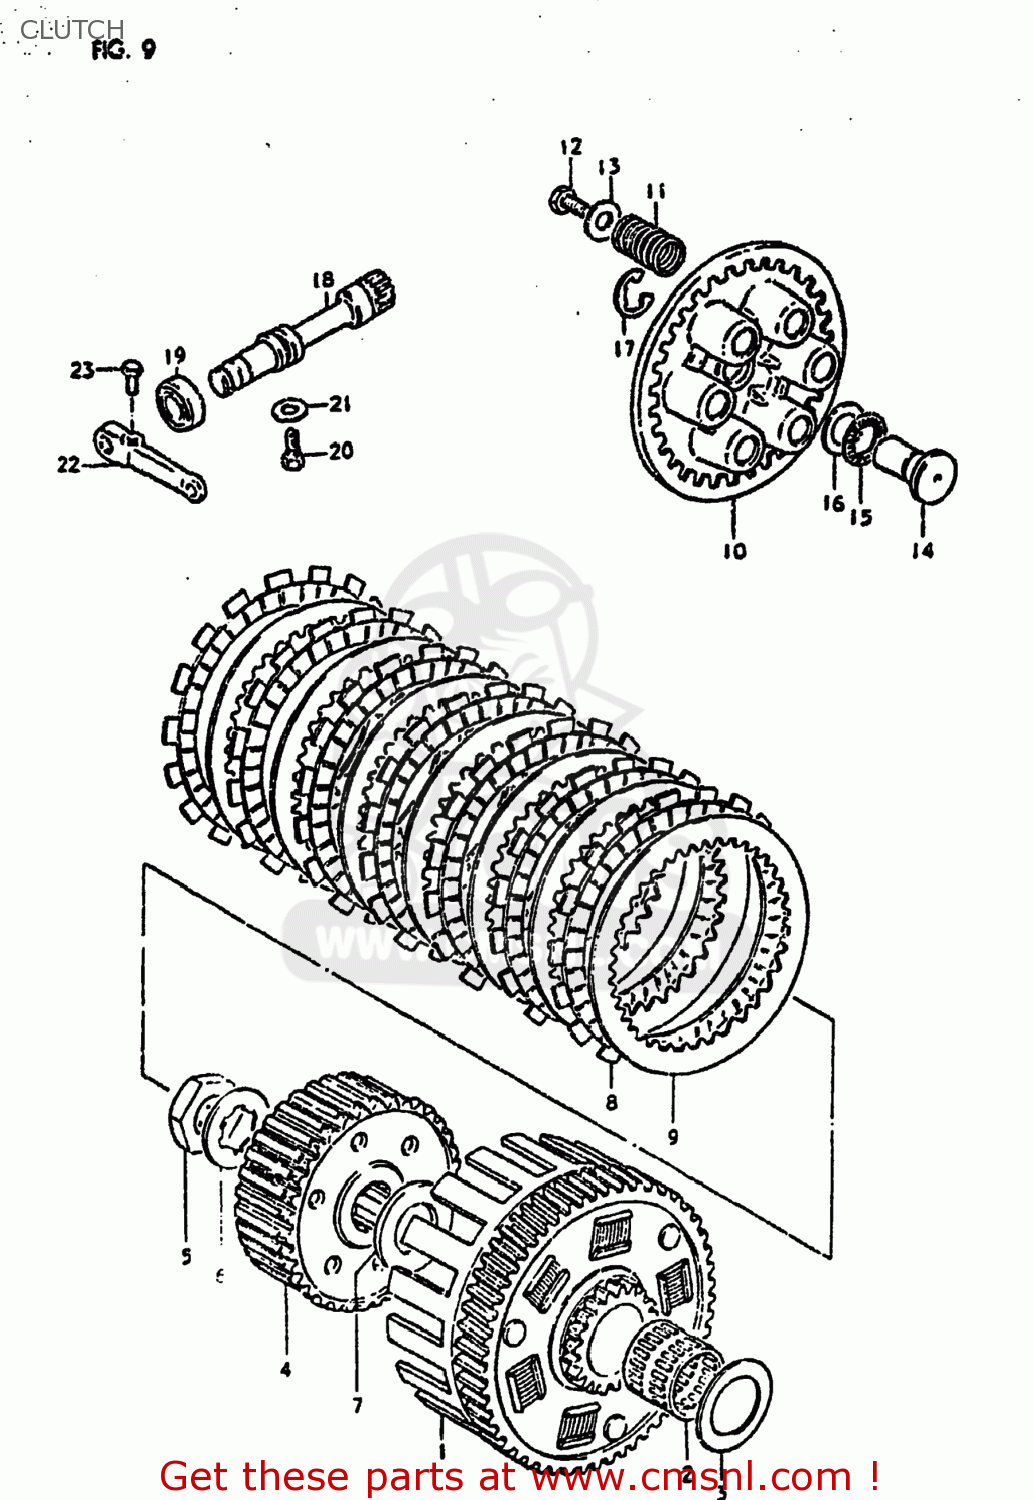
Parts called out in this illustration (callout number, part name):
1	GEAR ASSEMBLY,PRIMARY DRIVE
2	ROLLER BEARING (25X30X3
3	WASHER(25X41X3)
4	HUB,CLUTCH SLEEVE
5	NUT (20MM)
6	WASHER,LOCK
7	WASHER(20X44X3)
8	PLATE,CLUTCH DRIVE (MCA)
9	PLATE,CLUTCH DRIVEN(T:2.0) (NAS)
10	DISC,CLUTCH PRESSURE
11	SPRING
12	BOLT, UPPER
13	WASHER
14	RACK,CLUTCH RELEASE
15	BEARING(15X28X2)
16	WASHER
17	E RING 12MM
18	PINION,CLUTCH RELEASE
19	OIL SEAL
20	BOLT(6X12)
21	WASHER
22	ARM,CLUTCH RELEASE
23	BOLT
